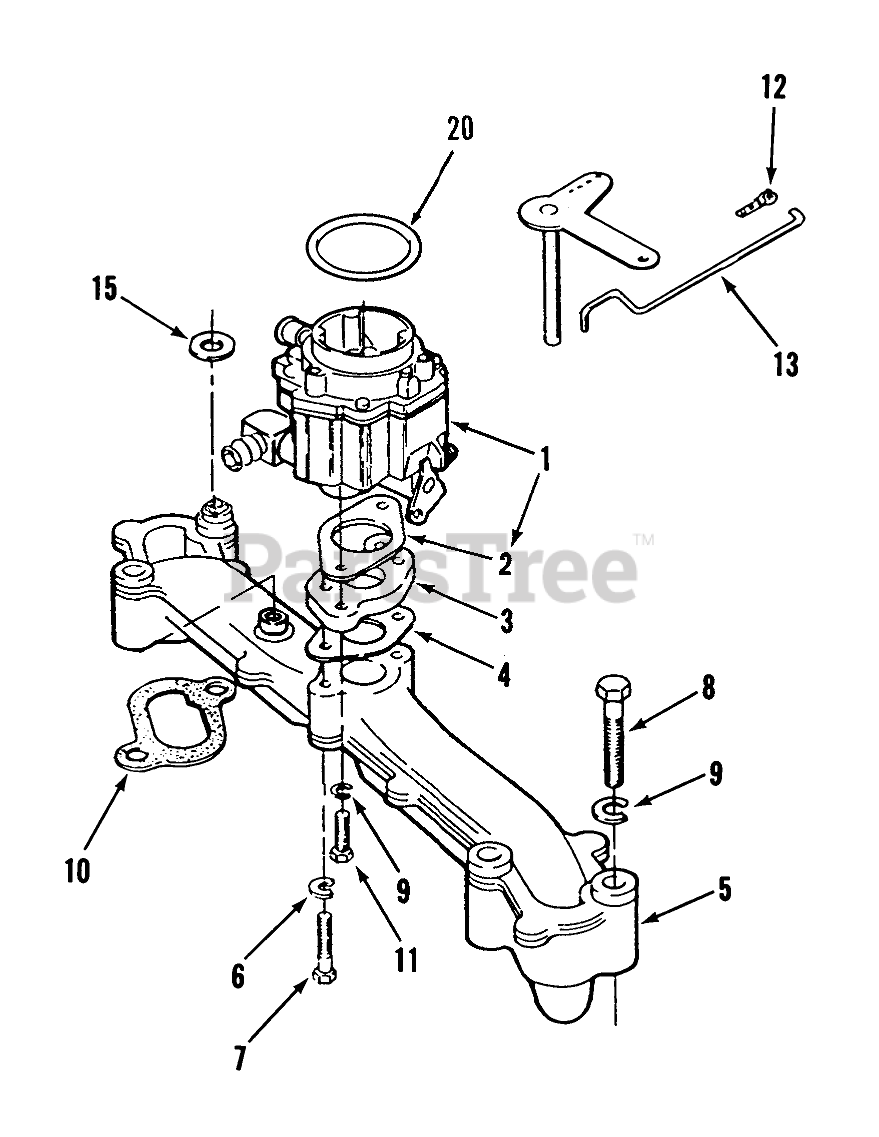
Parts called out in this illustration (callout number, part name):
1	Carburetor (Includes Mounting Gasket, Elbow and "O" Ring) see section 9-17 for complete carburetor breakdown
2	Gasket
3	Fitting-Barbed
4	Gasket
5	Intake Manifold
6	Washer-Lock
7	Screw Hex Hd. 1/4-20 x 1-3/8
9	Washer
10	Gasket
11	HHCS 5/16-18 X 1
12	Retaining Clip
13	Governor Control Rod
15	FLAT WASHER
